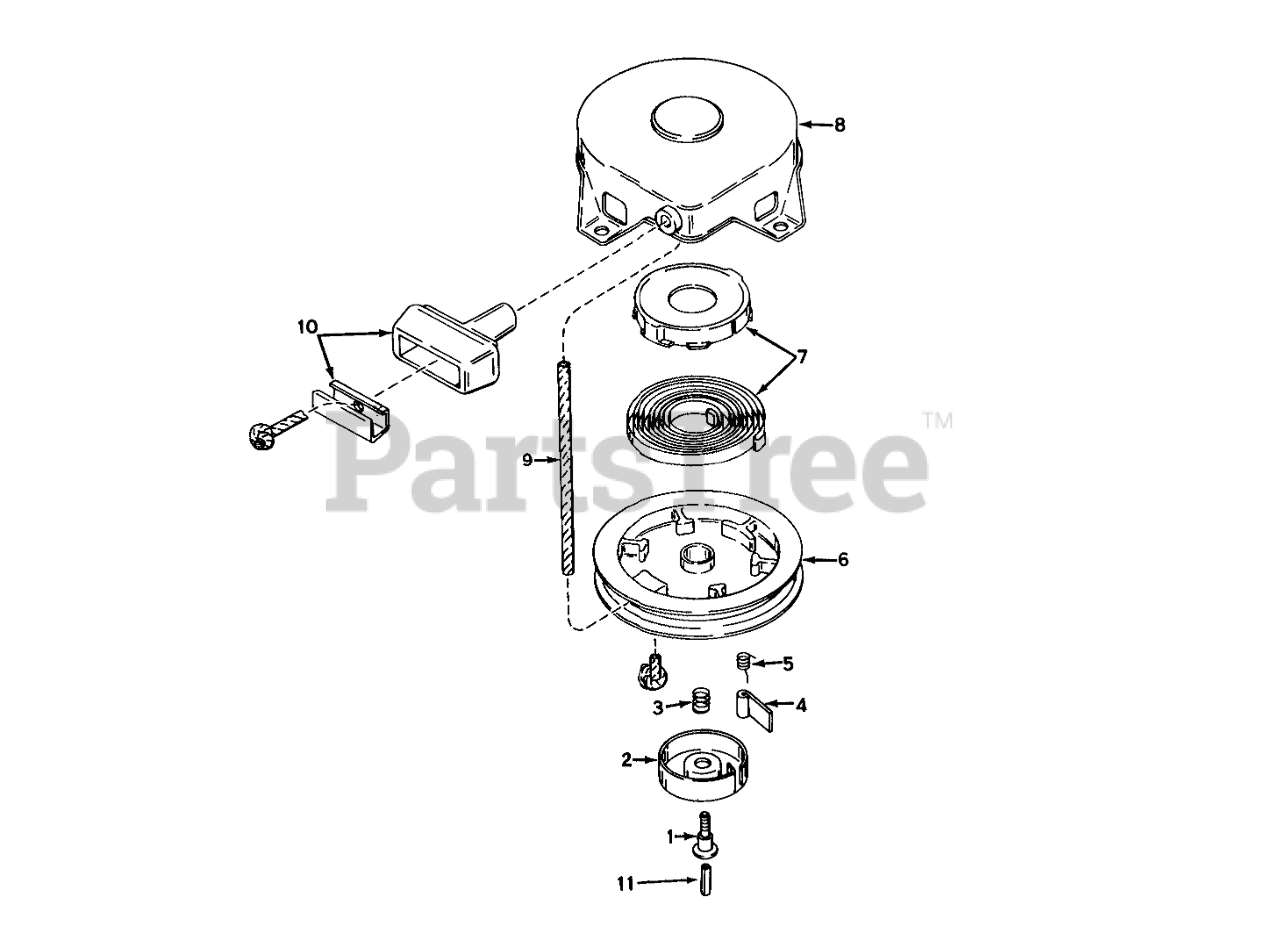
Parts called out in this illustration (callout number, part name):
1	Screw
2	Retainer
3	Spring-Brake
4	Dog-Starter
5	Spring-Dog
7	Spring & Keeper Assy
8	STARTER HOUSING ASSY
9	Rope Starter
10	Assy., Starter
11	Centering
